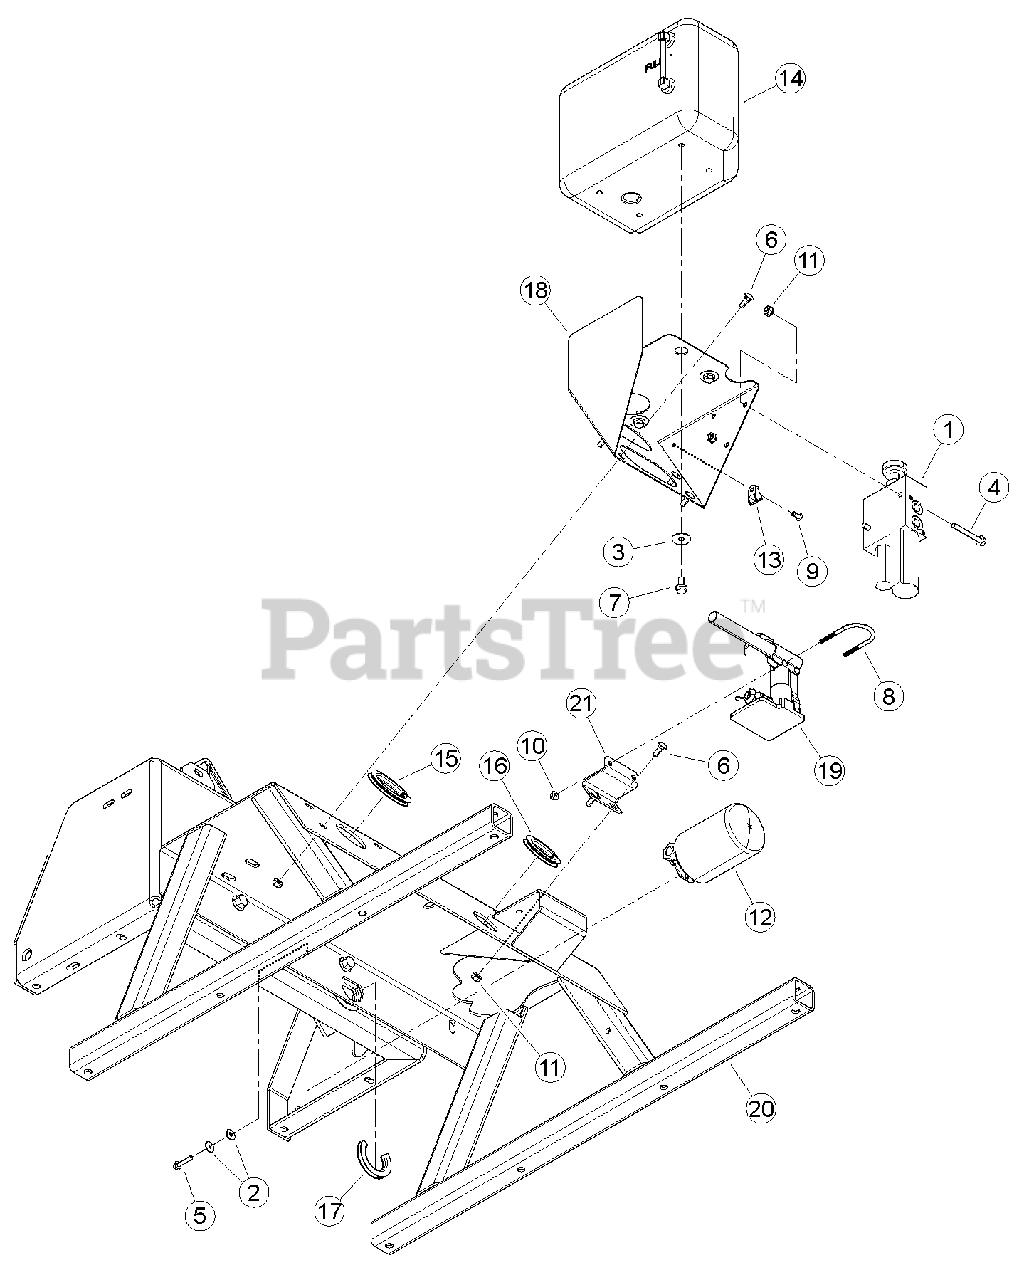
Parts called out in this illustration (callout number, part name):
1	VALVE, HYDRAULIC CONTROL
2	WASHER, 1/4" FLAT ZP
3	WASHER, 3/8" FENDER ZP
4	BOLT, 5/16 X 2-1/2 FLANGE NC
5	BOLT, 1/4 X 1-1/4 FLANGE NC
6	BOLT, 5/16 X 7/8" GR5 CRG NC ZP
7	BOLT, 3/8 X 3/4" SERRATED FLANGE
8	U-BOLT, 1/4 X 1-1/2 PIPE
9	RIVET, AL BLIND 1/4 X 3/4 DOME HEAD
10	NUT, 1/4-20 NYLOCK FLANGE
11	NUT, 5/16-18 NYLOCK FLANGE
12	ASSEMBLY, HYDRAULIC FILTER
13	CLAMP, CABLE MOUNT
14	TANK, HYDRAULIC
15	TRIM, SLOT EDGE COVER
16	TRIM, SLOT EDGE COVER
17	TRIM, SLOT EDGE COVER
18	WELDMENT, RESERVOIR BASE
19	JACK, HYDRAULIC 2 TON
20	WELDMENT, PTO STAND
21	MOUNT, JACK
